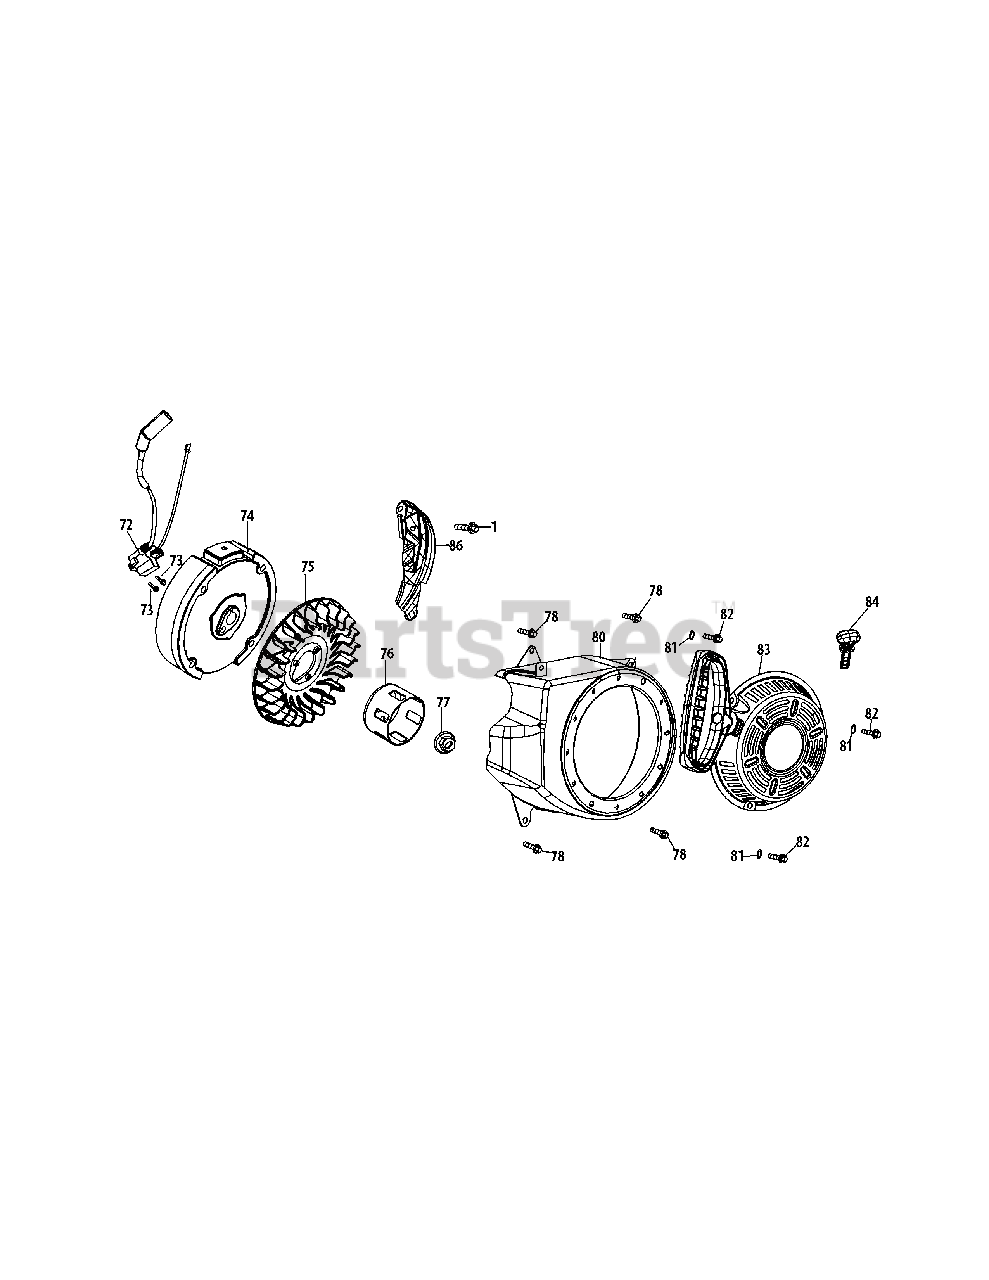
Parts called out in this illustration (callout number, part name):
1	Boltm6×16
72	Ignition Module
73	Bolt, Flange, M6×25
75	Fan, Flywheel
76	Cup, Starter
77	Nut M14×1.5
78	Bolt M6×14
80	Blower Housing
81	Gasket 6
82	Bolt M6×10
83	Starter, Recoil
84	Key
86	Flywheel Baffle
